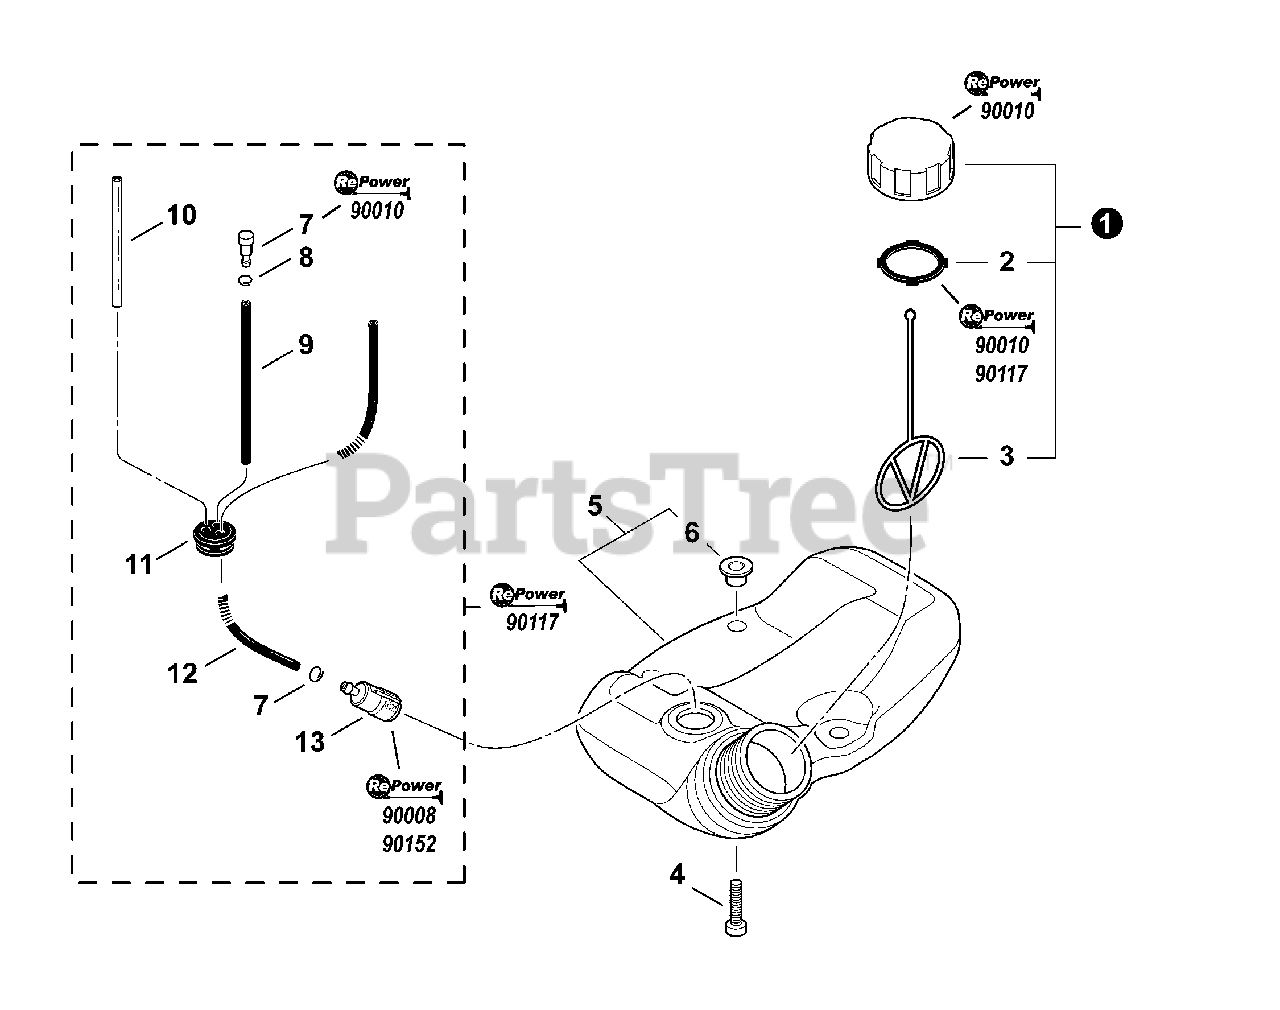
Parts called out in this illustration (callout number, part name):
1	CAP ASSY
2	GASKET, CAP
3	CONNECTOR, CAP
4	SCREW - 5×20
5	FUEL TANK ASSY
7	CLIP - 6
8	VENT, FUEL TANK
9	PIPE - 3×6×80 -- CLEAR
10	PIPE - 3×5×90 -- BLACK
11	GROMMET
12	PIPE - 3×5×210 -- BLACK
13	FILTER, FUEL
